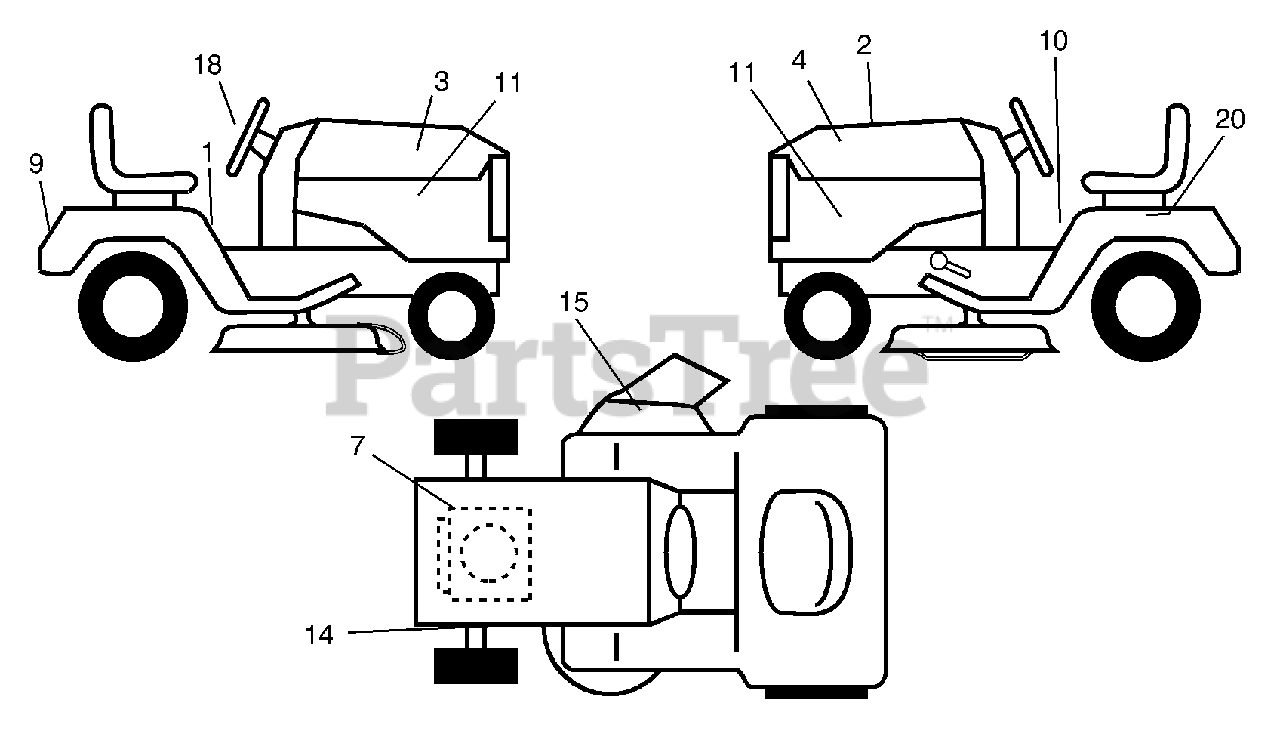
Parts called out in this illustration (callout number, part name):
1	Decal, Oper. Instr.
2	Decal, Replacement
3	Decal, Hood, R.H.
4	Decal, Hood, L.H.
7	Decal, HP Engine
9	Decal, Fender
10	Decal, Fender Danger
11	Decal, Hood Side
14	Decal, V-Belt Schematic
15	Decal, Deck B 42"
18	Decal, Steering
20	Decal, Battery Dngr/Psn Eng
